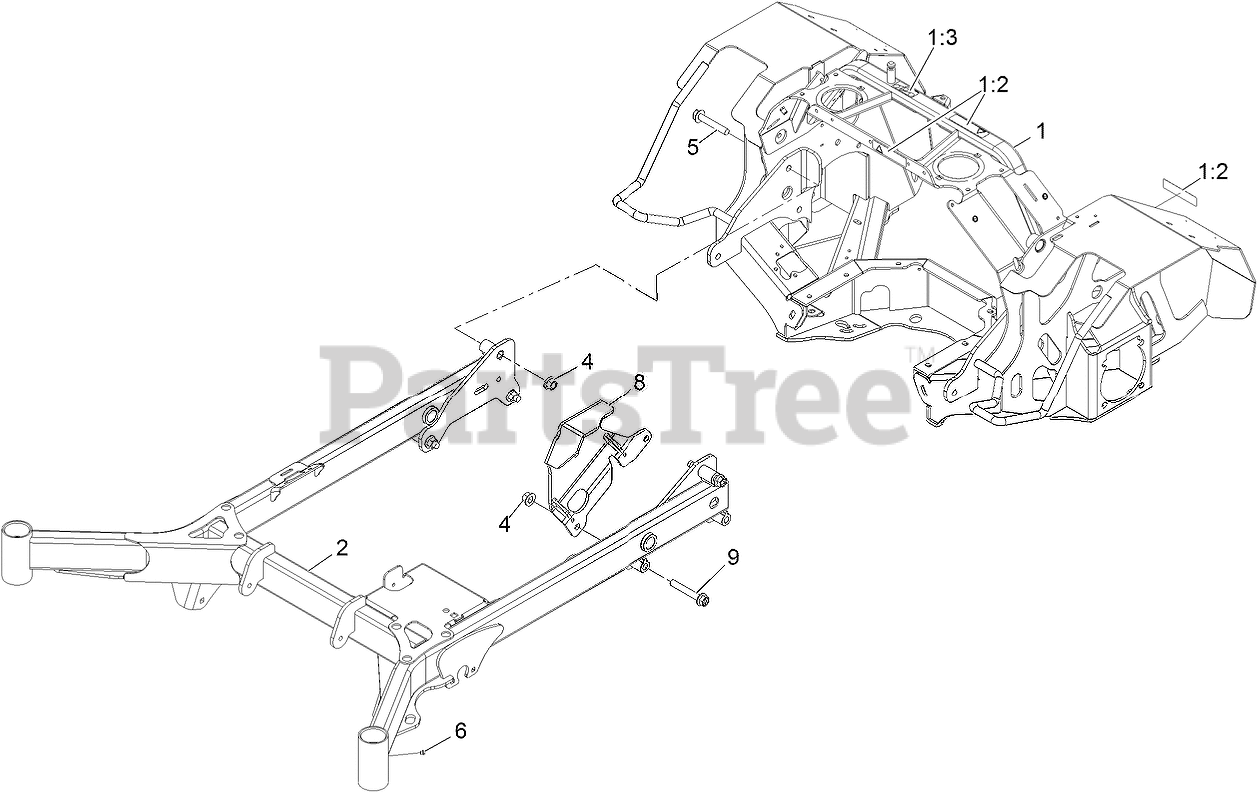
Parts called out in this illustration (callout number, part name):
1	ASM, Rear Frame W/Decals
1:2	DECAL-WARNING
1:3	DECAL-BELT ROUTING HYD
2	Weld, Front Frame, 60
4	Nut-Lock 1/2-13
5	SCREW-HF
